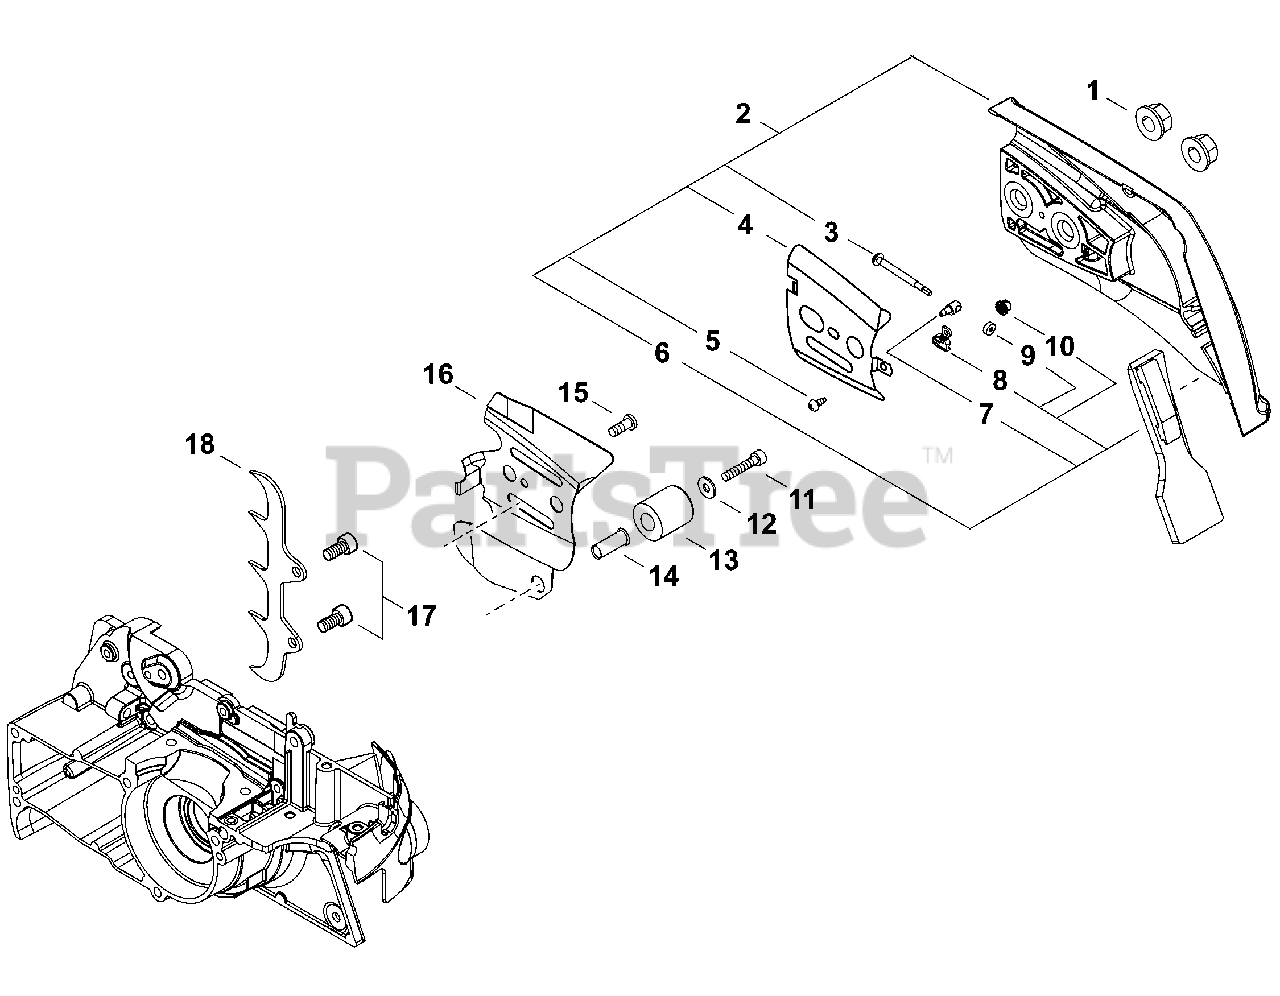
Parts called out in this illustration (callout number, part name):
1	NUT, FLANGE M8×1.25
2	COVER ASSY, CLUTCH
3	SCREW, CHAIN TENSION
4	PLATE, GUIDE - OUTER
5	SCREW 4×8
6	PROTECTOR
7	TENSIONER, CHAIN
8	COLLAR 8
9	GEAR, BEVEL
10	GEAR, BEVEL
11	BOLT 5×30
12	WASHER, FLAT 5.5×10×0.8
13	CHAIN CATCHER
14	COLLAR 5
15	SCREW M4×7
16	PLATE, GUIDE - INNER
17	BOLT 5×12
18	SPIKE, BUMPER
